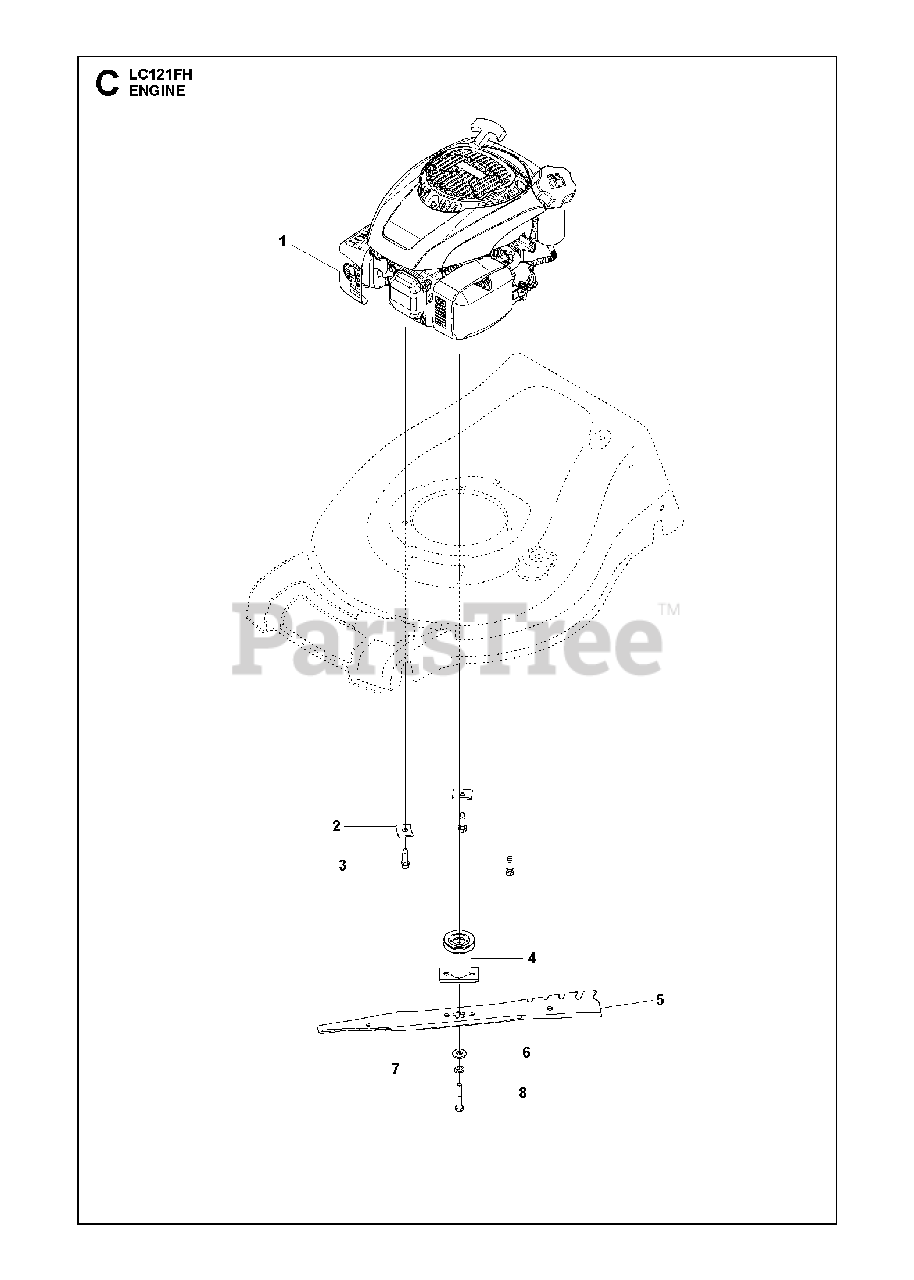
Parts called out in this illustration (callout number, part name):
2	WASHER.ENGINE.BZP
3	BOLT 3/8-16X1-1/8
4	Blade Adapter
5	BLADE.21.REAPER.WO/NOTCHES
6	WASHER,HARDEN
7	LOCKWASHER
8	BOLT.ENGINE.PULLEY
